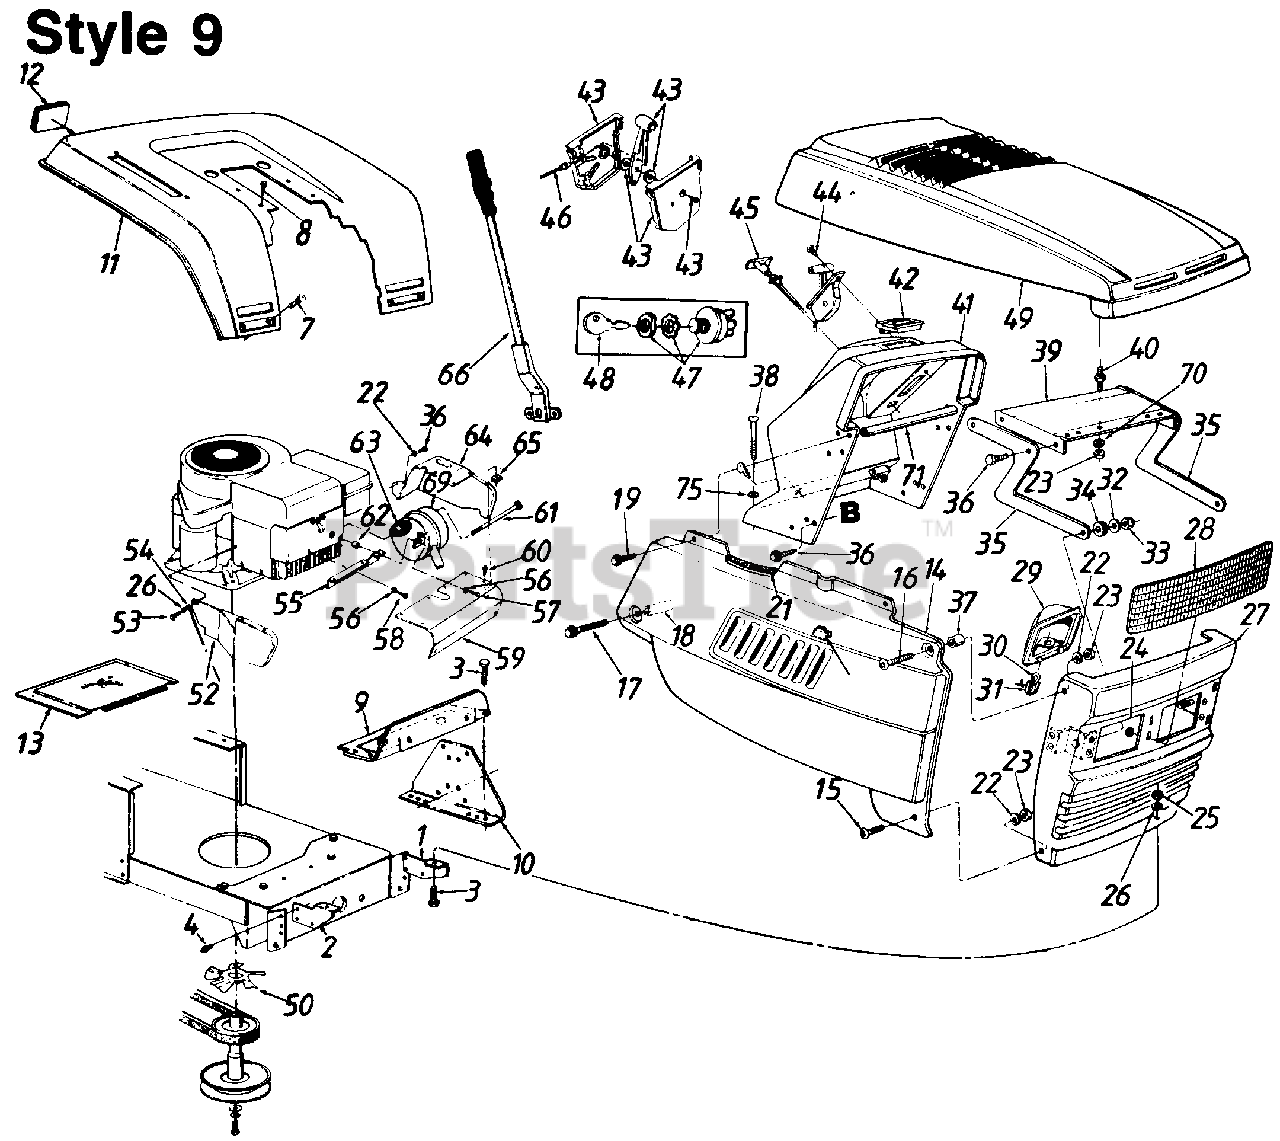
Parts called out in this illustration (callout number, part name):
1	Grille Mtg. Brkt.-L.H.
4	Hex Wash. Hd. Tap Scr. 5/16-18 x .5" Lg.
7	Carriage Bolt 1/4-20 x .5" Lg.
8	Hex Wash. Hd. Tap Scr. 5/16 x .75" Lg.
9	Support Bracket
10	Dash Support Bracket
13	Transmission Cover
14	Side Panel-R.H.
15	Truss Mach. Scr. 1/4-20 x .5" Lg.
16	Truss Mach. Scr. 1/4-20 x 1.0" Lg.
17	Hex Wash. TT-Tap Scr. 1/4-20 x 1.75" Lg.
18	Spacer .26" I.D. x 1.32"
19	Hex Rolling Tap Scr. 1/4-20 x .75" Lg.
21	Trim Strip-12" Lg.
22	L-Wash. 1/4" I.D.
23	Hex Nut 1/4-20 Thd.
24	Speed Nut 5/16" Thd.
25	Hex Nut 5/16-18 Thd.
26	L-Wash. 5/16" I.D.
29	Headlamp Housing
30	Headlamp
31	Twist Lock Lamp Socket
32	Bell-Wash. .345" I.D. x .88"
33	Hex L-Nut 5/16-18 Thd.
34	Rubber Washer
35	Hood Hinge
36	Hex Wash. Hd. B-Tap Scr. 1/4-20 x .5" Lg.
37	Spacer .265" I.D. x .376"
38	Carr . Bolt 1/4-20 x l.5"
39	Hood Plate
40	Double Ended Stud 1/4-20 Thd.
42	Ammeter
43	Throttle Control Box Ass'y.
44	Mach. Scr. #10 x .44" Lg.
45	Choke Control 29" Lg.
46	Throttle Control Wire
47	Ignition Switch
48	Ignition Key
52	Muffler Heat Shield-R.H.
53	Truss Mach. Scr. 5/16-18 x .75" Lg.
54	Ground Wire
55	Heat Shield Bracket
56	Spr. Wash. 1/4" I.D.
57	Hex Bolt 1/4-20 x .85" Lg.
58	Hex Bolt 1/4-20 x 3/8" Lg.
59	Muffler Heat Shield-Front
60	Hex AB-Tap Scr. #10 x .5" Lg.
61	Shoulder Bolt
62	Spacer
63	Exhaust Gasket
64	Muffler Heat Shield-L.H.
65	Speed Nut #10-24 Thd.
66	Lift Handle
69	Muffler
70	Bell-Wash. .265" I.D. x .75"
71	Grille Support Tube
75	Retaining Nut
